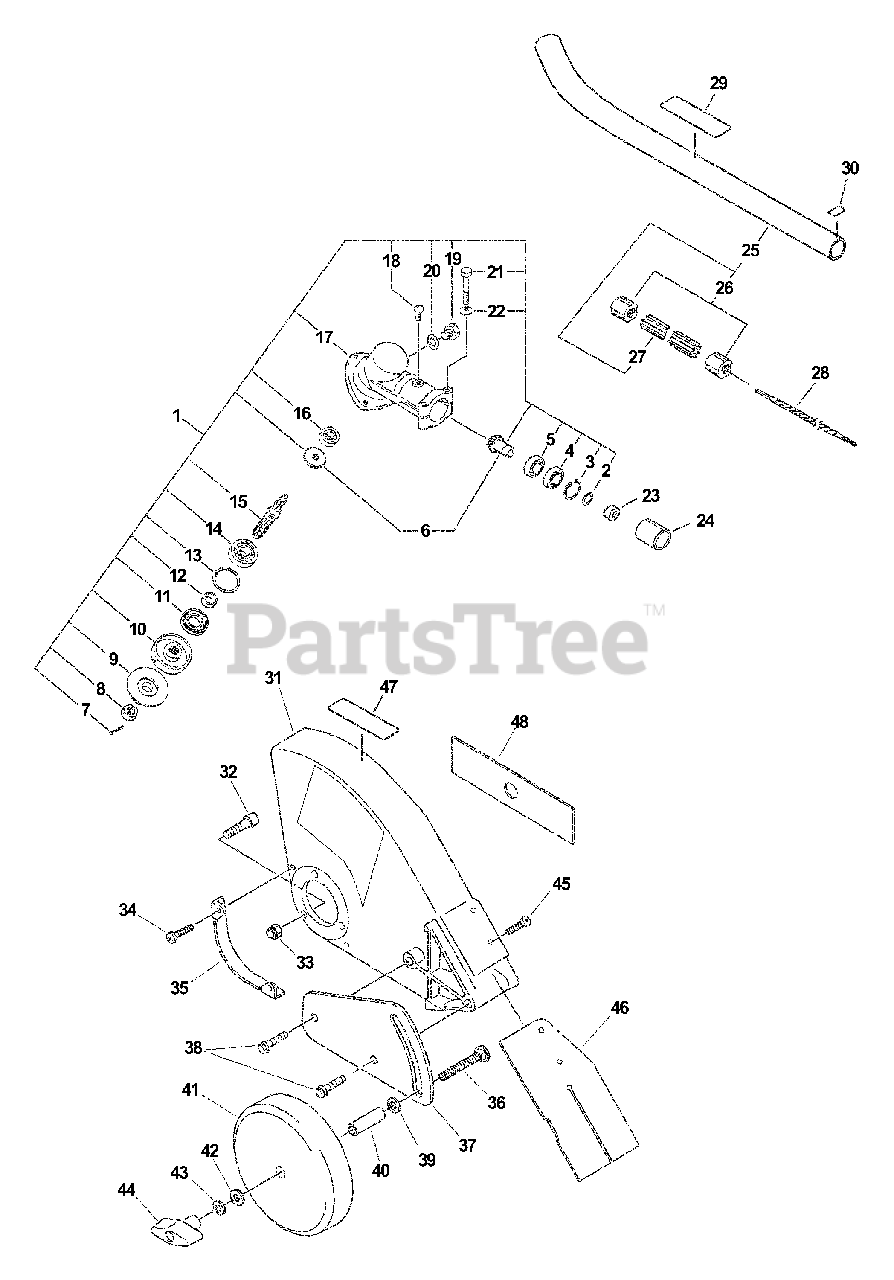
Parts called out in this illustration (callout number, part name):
1	GEAR CASE ASSY
2	RING, RETAINING - 18
3	RING, RETAINING
4	BEARING, BALL - 609
5	BEARING, BALL - 609
6	GEAR SET
7	PIN, SPLIT - 2X22
8	NUT - 10 -- LEFT HAND
9	ADAPTOR, BLADE - LOWER
10	ADAPTOR, BLADE - UPPER
11	SEAL, OIL
13	RING, RETAINING - 20
14	BEARING, BALL - 6201
15	GEAR - SHAFT
16	BEARING, BALL - 629
17	CASE, GEAR
18	SCREW - 5X12
19	FITTING, GREASE
21	BOLT - 5X30
22	WASHER - 5
23	CUSHION
25	MAIN PIPE ASSY
27	LINER - FLEXIBLE
28	DRIVESHAFT - FLEXIBLE
29	LABEL - CAUTION
30	LABEL - ALIGNMENT
31	SHIELD, DEBRIS
32	SCREW - 5X22
33	LOCKNUT - 5
34	SCREW - 4X16
36	BOLT - CARRIAGE
37	BRACKET, WHEEL
38	BOLT - 8
39	WASHER - 10
40	COLLAR - 12
41	WHEEL - 6X1.5
42	WASHER - 8
43	LOCKWASHER - 8
44	WINGNUT - 5/16-18
45	SCREW - 3
46	FLAP, DEBRIS
47	LABEL - CAUTION -- SPANISH
48	BLADE, EDGER
